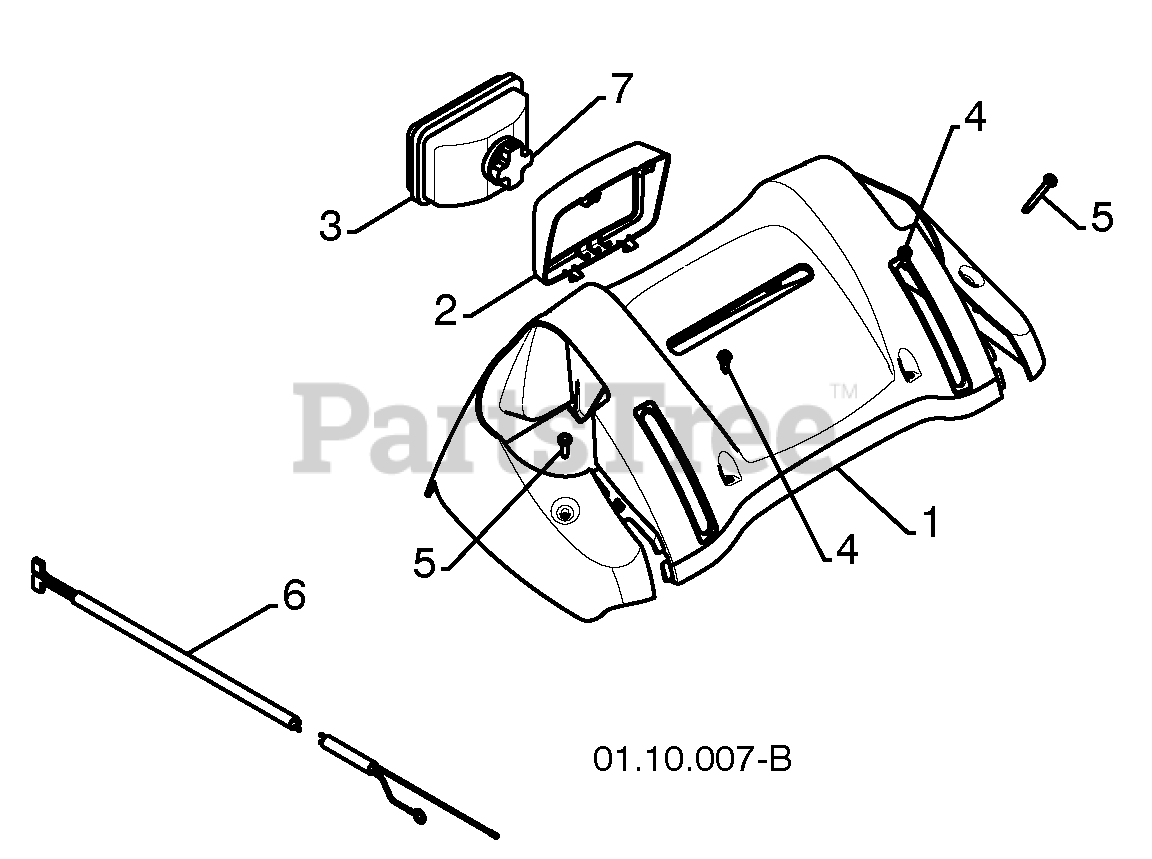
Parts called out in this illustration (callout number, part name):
1	CONSOLE PANEL
2	HEADLIGHT BEZEL
3	FLOOD HEADLIGHT
4	SHOULDER SCREW 10-24 X .625
5	SCREW 10-24 X 1.25
6	WIRE HARNESS
7	BULB
